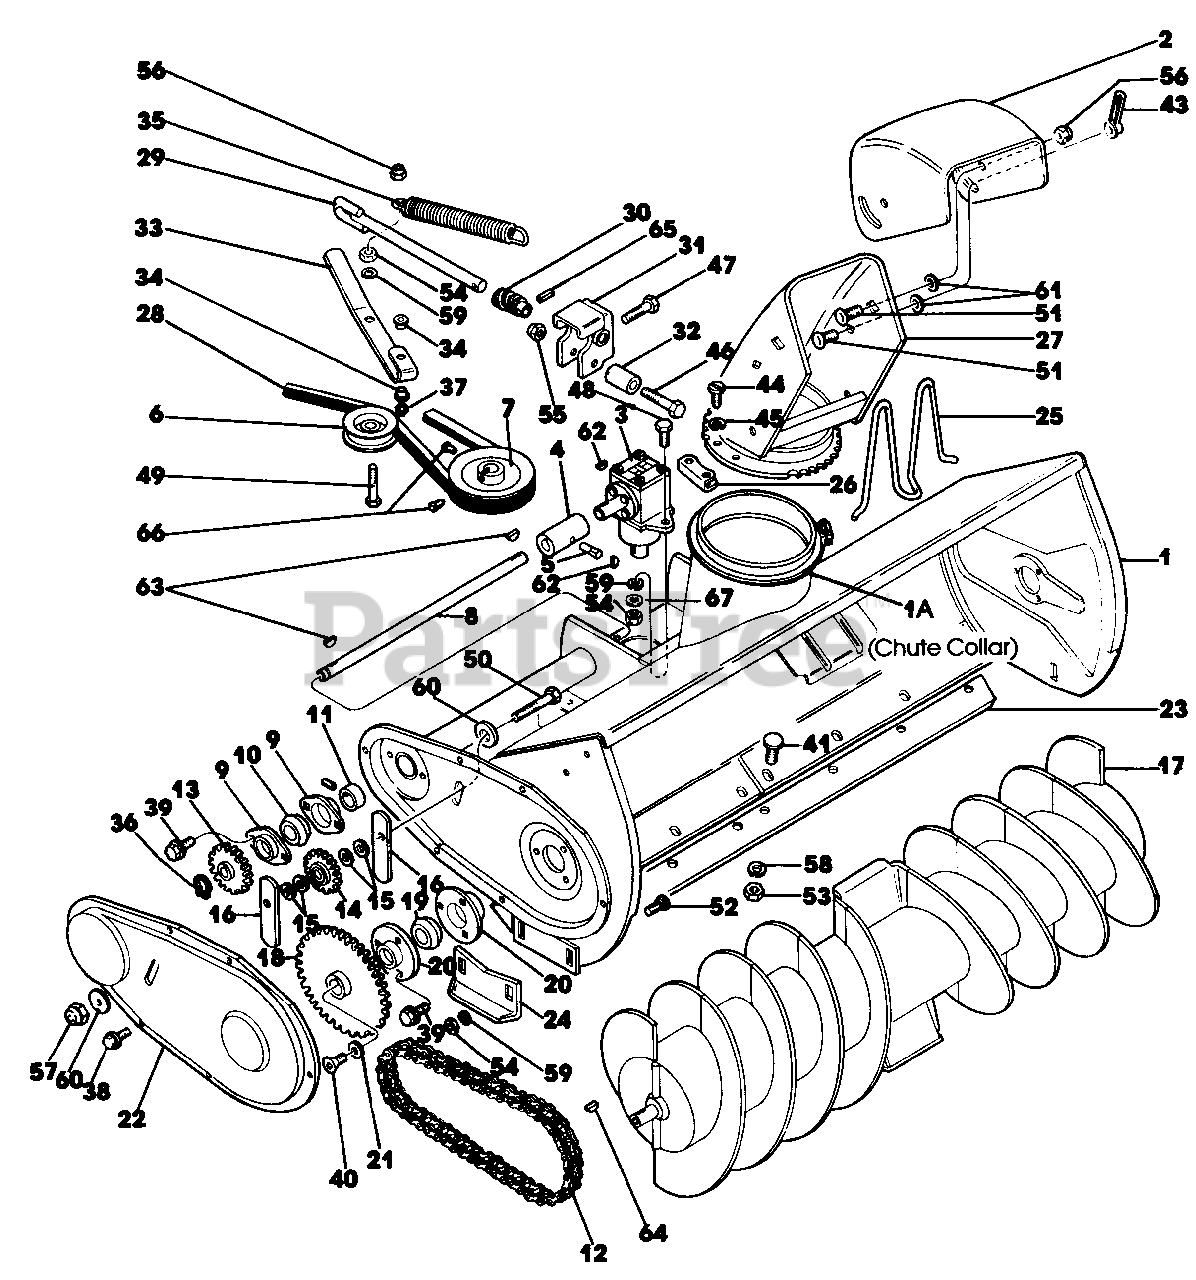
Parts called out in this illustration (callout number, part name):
1	Collector Housing Assembly w/Decal
1A	Chute Collar
2	Chute Deflector & Decal Assembly
3	Gear Box-R.H.
4	Coupling
5	Drive Pin-Grooved
6	Idler Pulley
7	Pulley-4-1/2 Dia.
8	Output Shaft
9	Flangette Stamping
10	Bearing
11	Collar w/Setscrew
12	Chain
13	Sprocket Assembly
14	Idler Sprocket
15	Spacer
16	Strip
17	Collector Assembly
18	Sprocket Assembly
19	Bearing
20	Flangette Stamping
21	Washer
22	Drive Cover
23	Scraper Blade
24	Skid
25	Discharge Guard
26	Retainer
27	Discharge Guide Assembly
28	V-Belt (Secondary)
29	Worm Shaft Assembly
30	Worm Gear
31	Worm Support
32	Spacer-Worm Support
33	Idler Arm Assembly w/Bushings
34	Bushing
35	Spring-Idler
36	Snap Ring
37	Snap Ring
38	Lock Screw 1/4-20 x 1/2
39	Lock Screw 5/16-18 x 1/2
40	Flat Socket Hd. Screw 5/16-18 x 3/4
41	Wafer Hd. Bolt 5/16-18 x 3/4
43	Wing Nut
44	Screw, Self Tapping #6-32 x 3/8
45	Lock Washer #6
46	Cap Screw, Hex Hd. 1/4-20 x 2 Plated, Grade 5
47	Cap Screw, Hex Hd. 5/16-18 x 1-1/2 Plated, Grade 5
48	Cap Screw, Hex Hd. 3/8-16 x 1-1/2 Plated, Grade 5
49	Cap Screw, Hex Hd. 3/8-16 x 2-1/4 Plated, Grade 5
50	Cap Screw, Hex Hd. 1/2-13 x 2 Plated, Grade 5
51	Bolt, Carriage 3/8-16 x 3/4 Plated
52	Bolt, Carriage 3/8-16 x 1" Plated
53	Nut, Hex 5/16-18 Plated
54	Nut, Hex 3/8-16 Plated
55	Nut, Hex Cone Lock 1/4-20 Plated
56	Nut, Hex Cone Lock 3/8-16 Plated
57	Nut, Hex Cone Lock 1/2-13 Plated
58	Washer, Spring Lock 5/16 Plated
59	Washer, Spring Lock 3/8 Plated
60	Washer, Flat SAE 1/2 Plated
61	Washer, Flat 1/2 Plated
62	Key, Woodruff 3/16 x 5/8 Grade 5
63	Key, Woodruff 3/16 x 3/4
64	Key, Woodruff 1/4 x 3/4
65	Pin, Roll 1/8 x 3/4 Plated
66	Setscrew, Square Hd. Cup Pt. 5/16-18 x 3/4 Plated
67	Washer, Flat SAE 3/8 Plated
